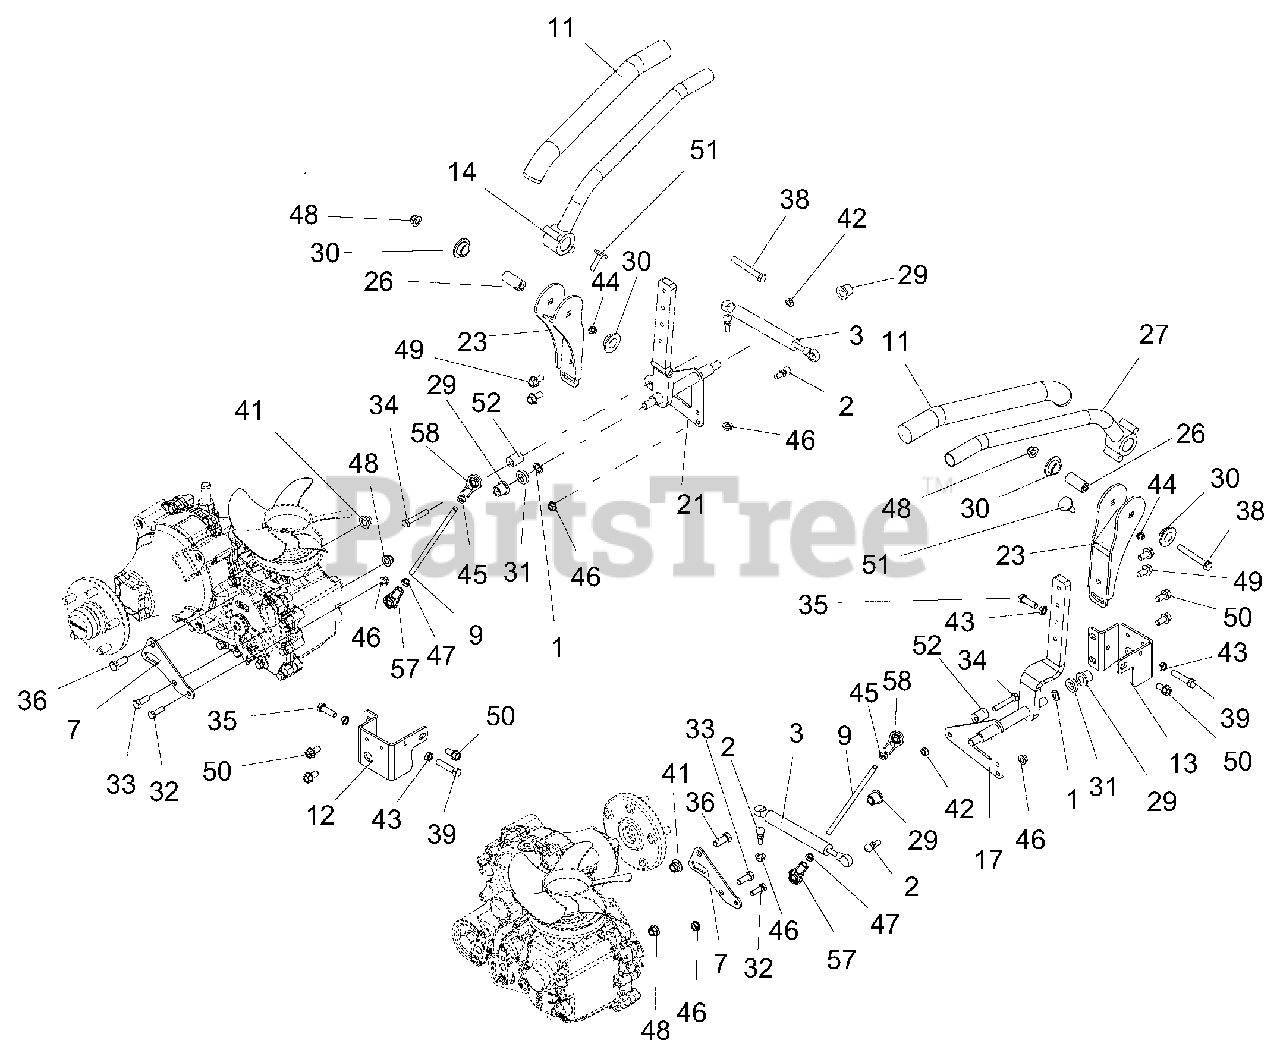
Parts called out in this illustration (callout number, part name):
1	WAVE WASHER .531X.781X.125 FH
2	STUD-BALL
3	DAMPER
7	BRKT., CONTROL MTG
9	ROD, STEERING
11	GRIP, HANDLEBAR
12	BRKT, RH CONTROL ARM STOP
13	BRKT, LH CONTROL ARM STOP
14	WLDMT, RH STEERING ARM
17	WLDMT, LH LOWER CONTROL ARM
21	WLDMT, RH LOWER CONTROL ARM
23	MOUNT, STEERING ARM, ADJUSTABLE
26	SPCR, STEERING ARM
27	WLDMT, LH STEERING ARM
29	BUSHING, PLASTIC
30	BUSHING, FLANGE
32	BLT-HEX .31-18X1.00 GR5 YWZC
33	BLT-HEX .38-16X1.00 GR5
34	BLT-HEX .31-18X2.00 GR5 YWZC
35	BLT-HEX .38-16X1.25 GR5 YWZC
36	BLT-HEX .44-14X1.00 GR5
38	BLT-RDHDSQSHK, 38-16X2.50 G5YZ
39	BLT-HEX .38-16X1.75 GR5 FTD YWZ
41	NUT-LK-NYL-FLG .44-14 YWZC
42	NUT-LK-CTR .31-18 YWZC
43	NUT, 3/8-16 JAM GR5
44	NUT, 5/16-18 JAM GR5
45	NUT-JAM
46	NUT, LK-TOP-FLG .312-18 YWZC
47	NUT, JAM -LH .31-24 YWZC
48	NUT-LK-NYL-FLG .38-16 YWZC
49	BLT-SERHFWH .38-16X.75 YWZC
50	SCR-TAP .38-16X.75 HWH TR YWZ
51	BUMPER, STUD MOUNTED
52	ECCENTRIC
57	LH ROD END
58	RH ROD END
